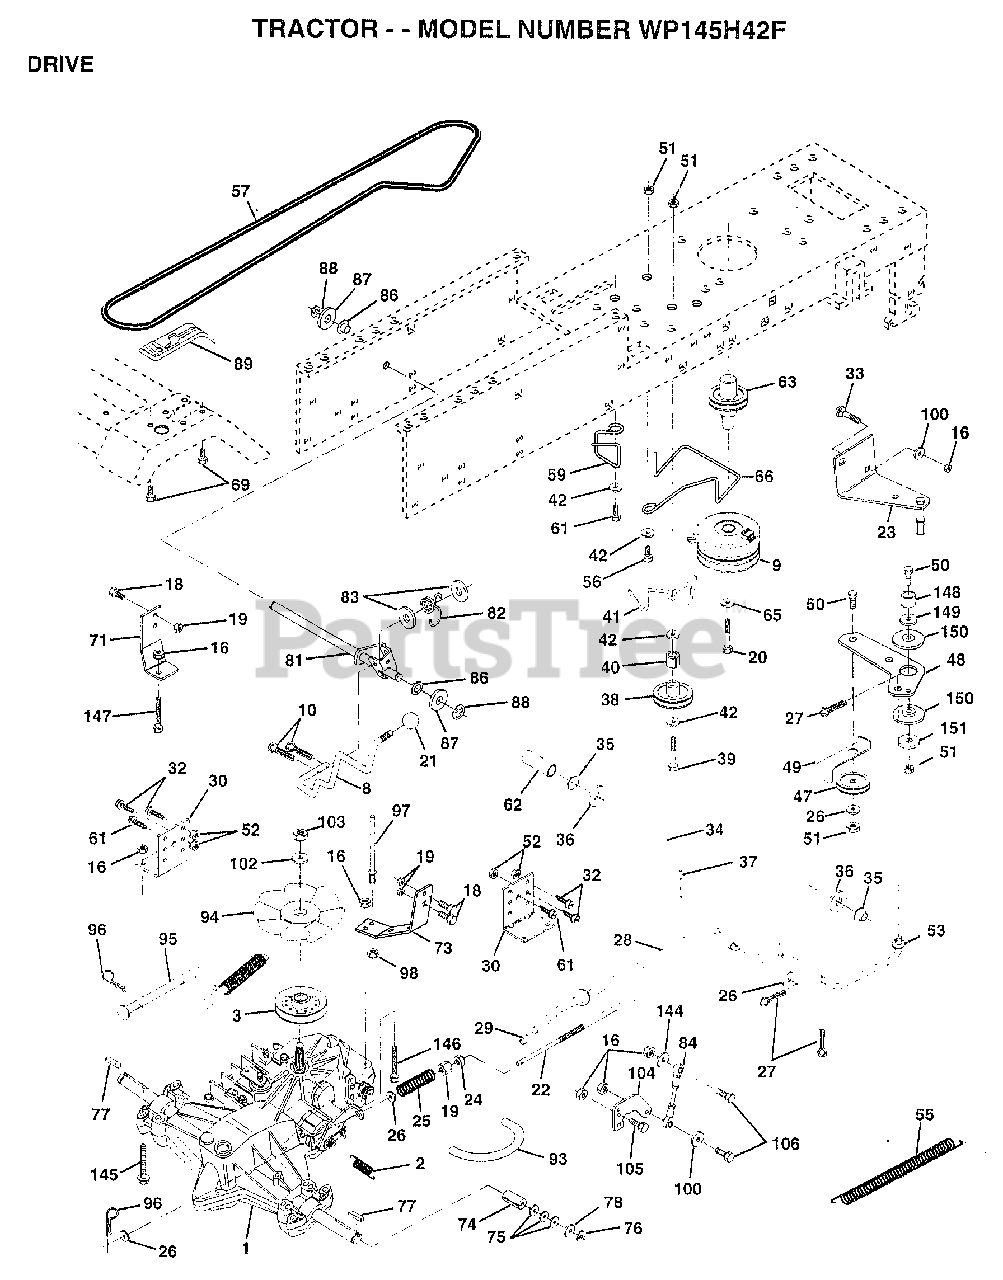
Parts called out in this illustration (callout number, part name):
1	TRANSAXLE.3100650
2	SPRING RET BRAKE
3	PULLEY.TRANSAXLE
8	ROD SHIFT FEND LT
9	CLUTCH.ELECT.EVX.
10	PIN COTTER 1/8
16	NUT
18	BOLT
19	NUT
20	BOLT.7/16-20X4.25
21	KNOB T (1/2-HOLE)
22	ROD.BRAKE.HYDRO.
23	BRACKET.CLUT.MTG.
24	NUT
25	SPRING ROD LT
26	WASHER
27	COTTER PIN
28	ROD.BRAKE.PARK.LT
29	PLUNGER CAP T
30	TRANSAXLE MTG BKT
32	BOLT
33	BOLT
34	SHAFT ASM-PEDAL F
35	NYLON BEARING
36	WASHER LT
38	PULLEY.IDLER.FLAT
39	BOLT
40	SPACER T
42	WASHER
48	BELLCRANK.CLUTCH
49	RETAIN BELT
53	"LINK, CLUTCH T"
55	"SPRING, RETURN LT"
57	"BELT.GD DRV 82"""
59	KEEPER BELT CNTSP
61	SCREW
62	PEDAL COVER T
63	PULLEY.CLUTCH.EVX
65	LOCKWASHER
66	KEEPER-BELT
69	SCREW HEXWSH H-L
71	STRAP TORQ LH HYD
73	"STRAP-TORQUE,RH"
74	SPACER SPLIT
76	E-RING LT
77	SQUARE KEY
78	WASHER
81	SHAFT.CROS.20.HYD
82	"SPRING,TORSION"
83	WASHER
84	ROD.TIE
86	BUSHING
87	WASHER D
88	KLIP RING
93	"LINE FUEL HYD 4"""
94	"FAN 7"" HYDRO"
97	BOLT KEEPER RH
98	NUT
100	WASHER M
102	WASHER BELLEVILLE
104	ARM CONTROL HYDRO
105	SCREW CAP 5/16-18
106	BOLT
144	WASHER
145	BOLT.HEX.FLGHD
146	BOLT.HEX.FLGHD.
147	BOLT.HEX.FLGHD
149	SPACER RETAINER
150	BUSHING.NYLON
151	WASHER
